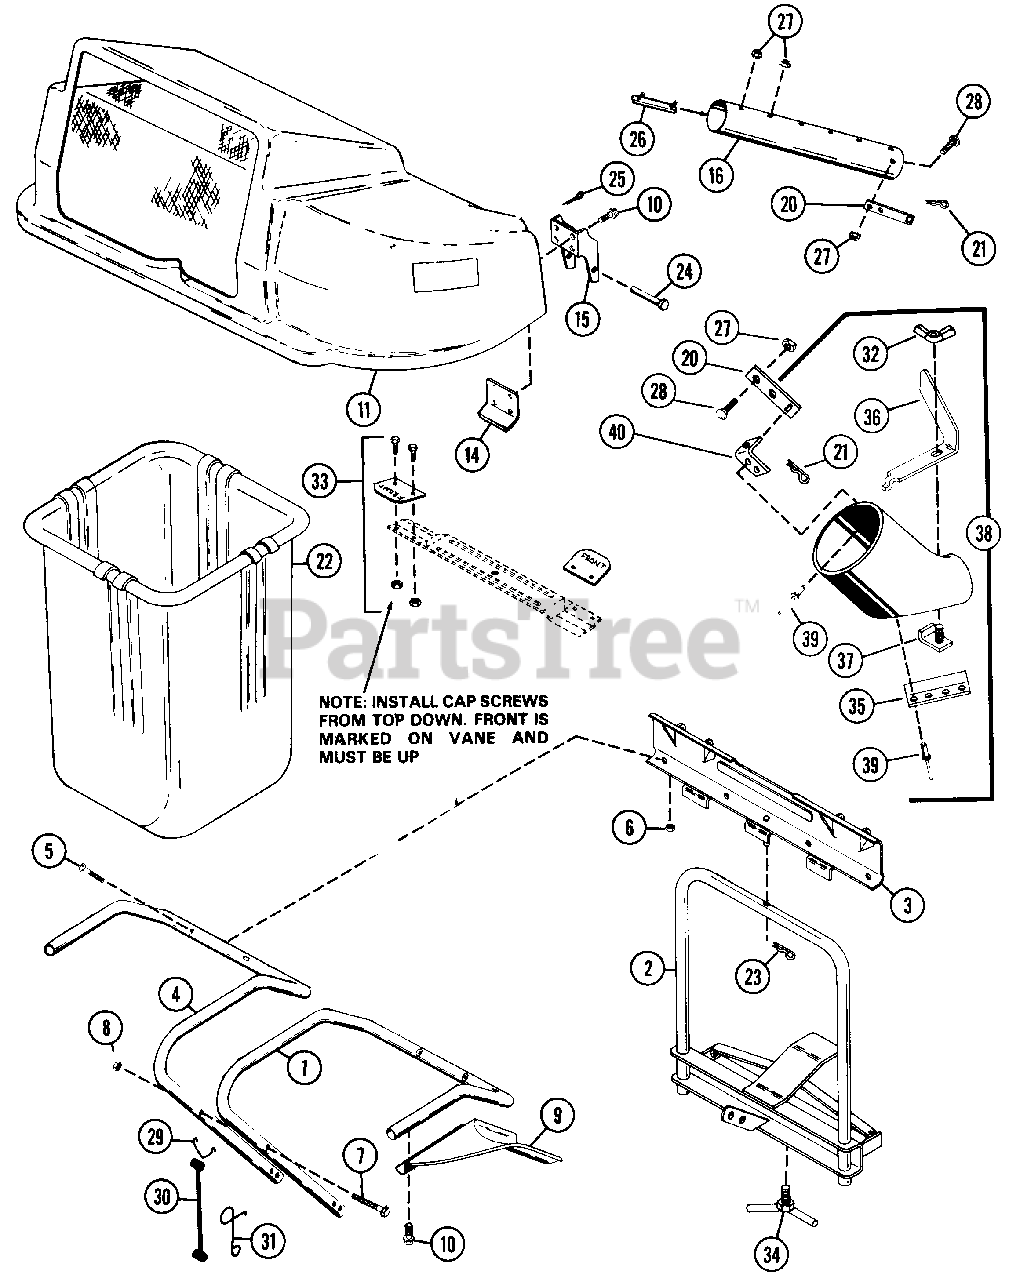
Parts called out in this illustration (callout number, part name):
1	TUBE, R.H. SUPPORT
2	ATTACHMENT FRAME
3	FRAME
4	TUBE, L.H. SUPPORT
5	SCREW, MACHINE 5/16-18X1.50
6	NUT, LOCK 5/16-18
7	CAP SCREW 1/4-2X2.25
8	NUT, LOCK 1/4-20
9	TUBE SUPPORT
10	SCREW, FLANGE 1/4-20X5/8
11	COVER
14	RETAINER
15	HINGE
16	TUBE BLANK
20	STRAP
21	HAIR PIN, COTTER 3/32X1-7/8
22	BASKET
23	HAIR PIN, INTERNAL
24	CLEVIS PIN
25	COTTER PIN 1/16X.50
26	CLIP
27	NUT, FLANGE 1/4-20
28	BOLT, CARRIAGE 1/4-20X.50
29	ANCHOR
30	STRAP
31	HOOK
32	NUT, WING 5/16-18
33	VANE ASM.
34	BOLT, T-HANDLE
35	CHUTE EXTENSION
36	BOOT STRAP
37	CONE CLIP
38	BOOT ASM.
39	RIVET
40	RETAINER
NS	DECAL, GRAVELY LOGO
